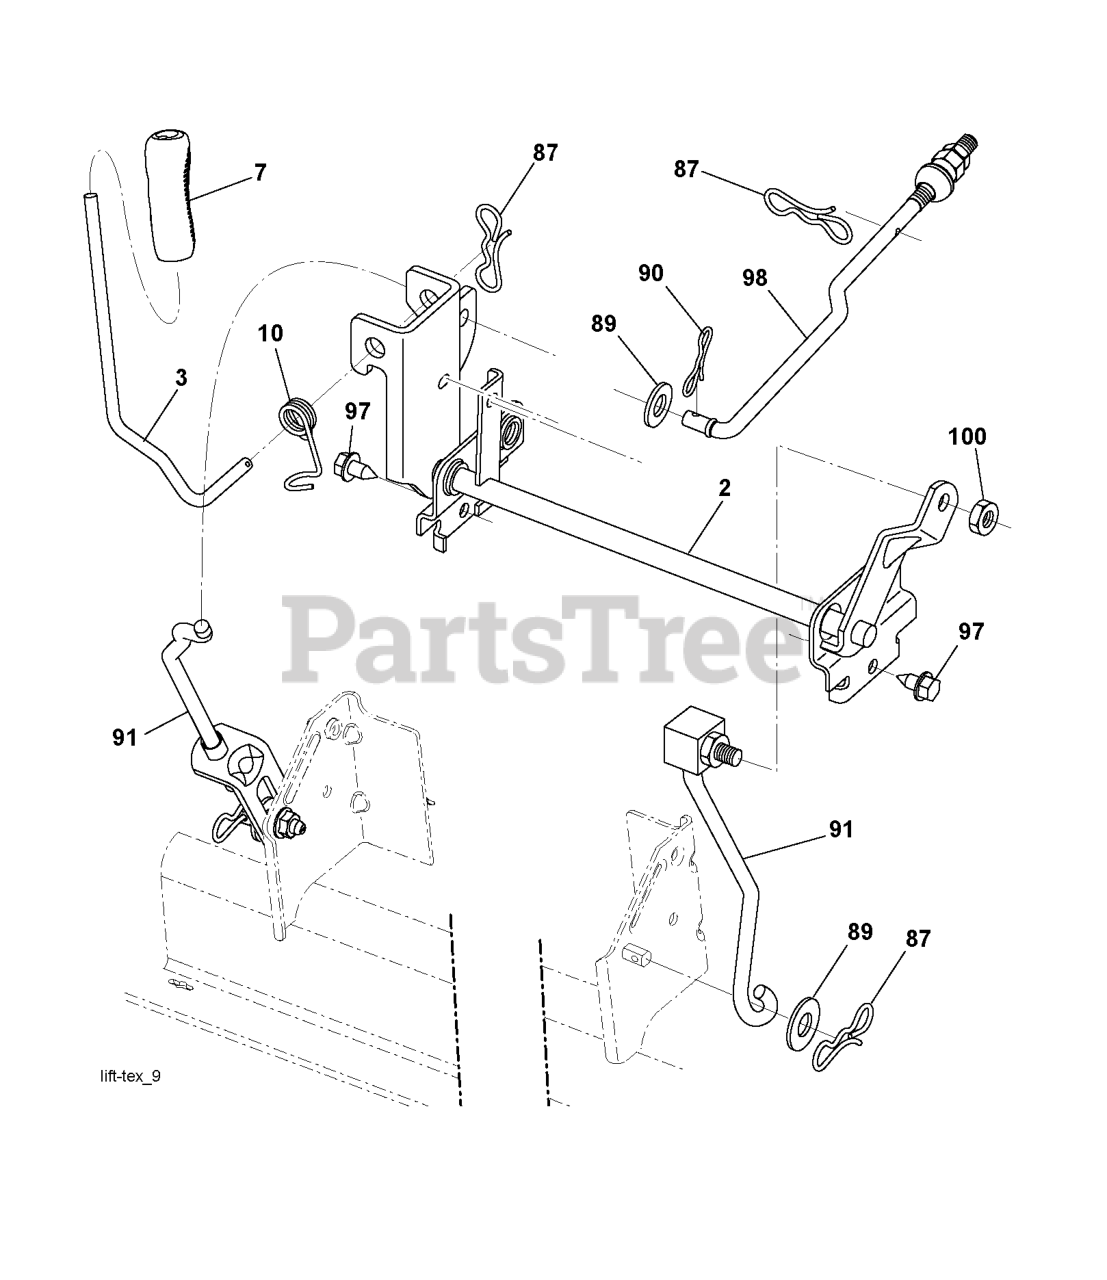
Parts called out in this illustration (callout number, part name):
2	SHAFT.ASM.LIFT.CROSS.H
3	LEVER.LIFT.HANDLE.LT
7	GRIP.LEVER.5625.ID
10	SPRING.TORSION.LIFT.HANDLE
87	PIN.COTTER.7/16.BOW TI.
89	WASHER.CLEAR.ZINC
90	PIN.COTTER.5/16.BOW TI
91	LINK.ASM.LIFT.REAR
97	SCREW 3/8-16X3/4
98	LINK.ASM.SUSP.FRONT.MW
100	LOCKNUT
